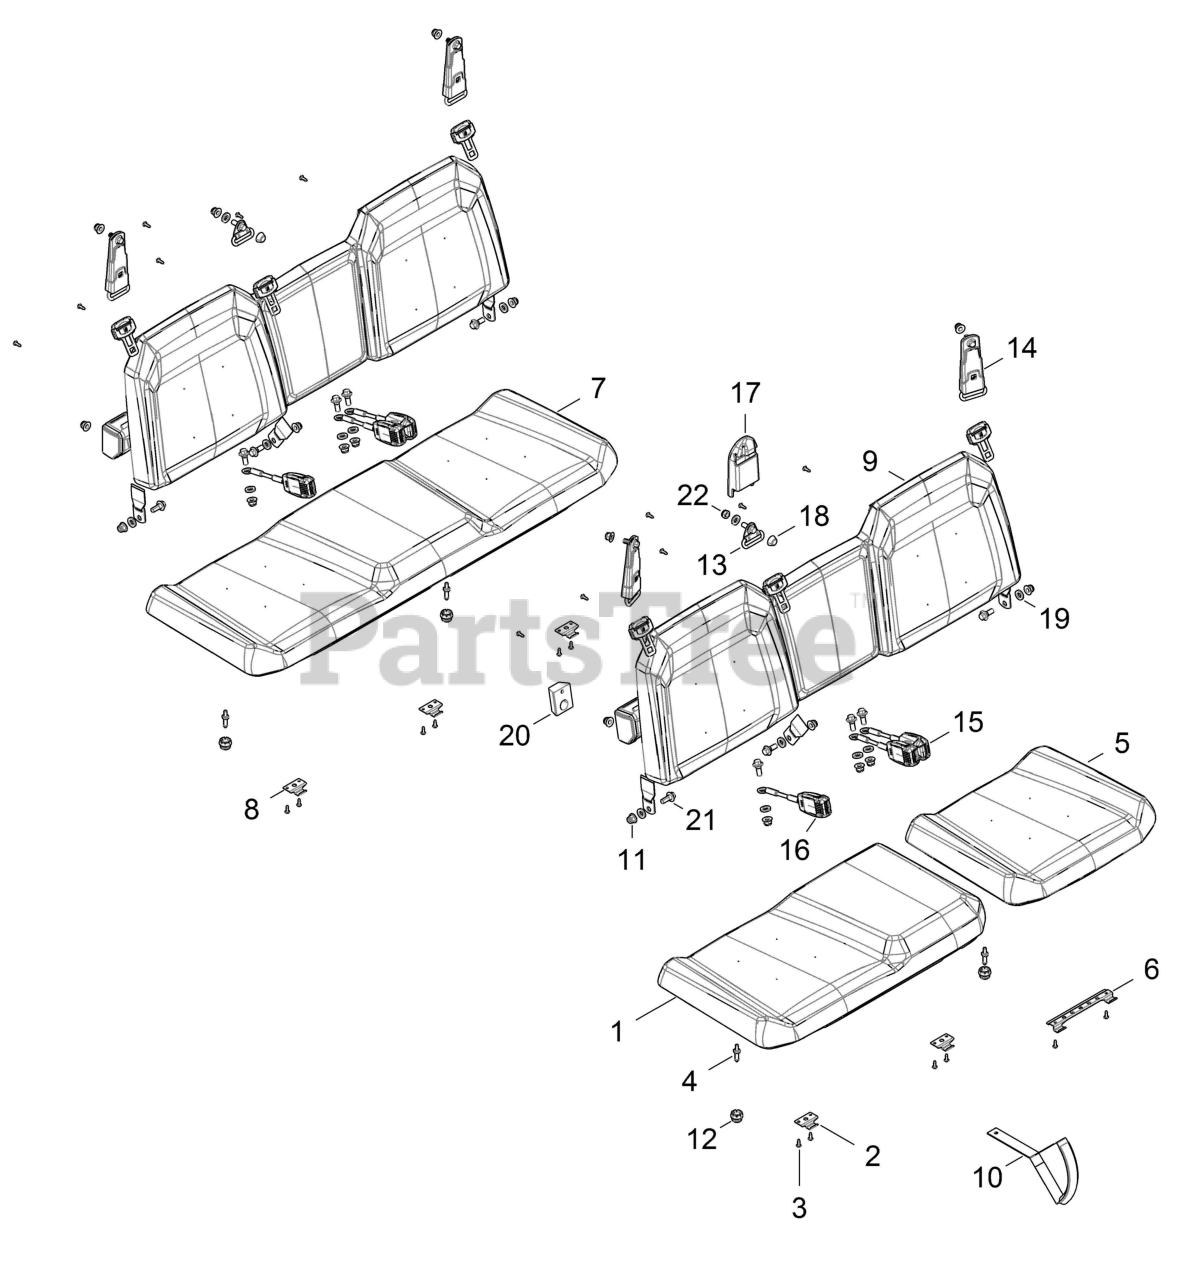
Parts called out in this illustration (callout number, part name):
1	ASM-SEAT,BTM,60,GRAVELY GRAY
2	BRKT-SEAT HINGE
3	SCR-TX TRUSS-#14X3/4,HI/LO ZBK
4	PIN-SEAT LATCH
5	ASM-SEAT,BTM,40,GRAVELY GRAY
6	BRKT-SEAT HINGE,DOUBLE
7	ASM.,SEAT,3 PASSENGER,BTM GRAY
8	BRKT-SEAT HINGE
9	ASM-SEAT,3PASS,BACK,GRVLY GRAY
10	STRAP, SEAT, CENTER
11	NUT-HXFL M12X1.75 NYLOC ZOD
13	ASM-SEAT BELT,3PT,CENTER
14	ASM-SEAT BELT,3PT
15	BUCKLE-SEATBELT,9.6,DRIVER
16	BUCKLE-SEATBELT,9.6,PASSENGER
17	COVER-SEAT BELT MOUNT
18	CAP-BOLT HEAD
19	WASHER-SEATBELT,RUBBER
20	PAD-REAR,SEAT BASE
21	SCR-HXFLSH-M12X1.75-M14X9 ZOD
22	NUT-NYLOK,M12X1.5,0600110
